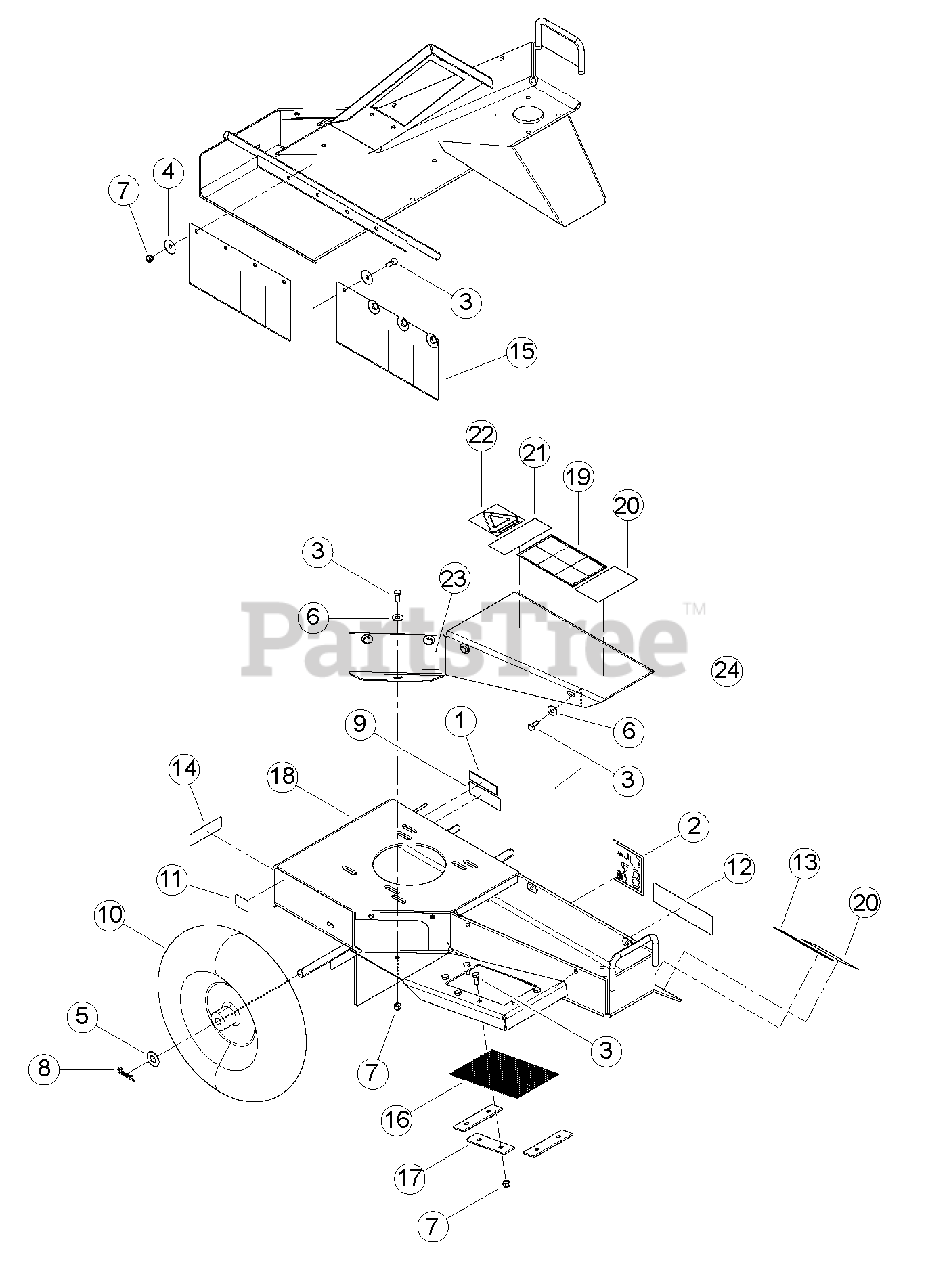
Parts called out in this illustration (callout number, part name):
1	DECAL, STUMPGRINDER INFO
2	DECAL, 87 DB
3	BOLT, 5/16 X 3/4 HEX HD GR5 ZP
4	WASHER, 5/16 FENDER ZP
5	WASHER, 5/8 SAE FLAT ZP
6	WASHER, 5/16 FLAT ZP
7	NUT, 5/16 NE NYLOCK ZP
8	HAIRPIN CLIP ZP #203
9	DECAL, SERIAL NUMBER
10	TIRE, 480/400 X 8 WHEELBARROW
11	DECAL, CE APPROVAL (WAS 16753, REMOVED)
12	DECAL, ECHO BEARCAT 6.82 X 1.90
13	DECAL, MODEL SG340
14	DECAL, ATLANTIC BRIDGE LTD INFO
15	MUD FLAP, STUMP GRINDER
16	DEBRIS SCREEN, STUMP GRINDER
17	SCREEN CLAMP, STUMP GRINDER
18	WELDMENT, STUMP GRINDER FRAME
19	DECAL, OPERATING INSTRUCTIONS ISO
20	DECAL, GRINDER DANGER
21	DECAL, MULTILINGUAL MANUAL
22	DECAL, SMALL RECLAIM IT
23	DECAL, ECHO BEAR CAT QR CODE
24	COVER, TOP STUMP GRINDER
